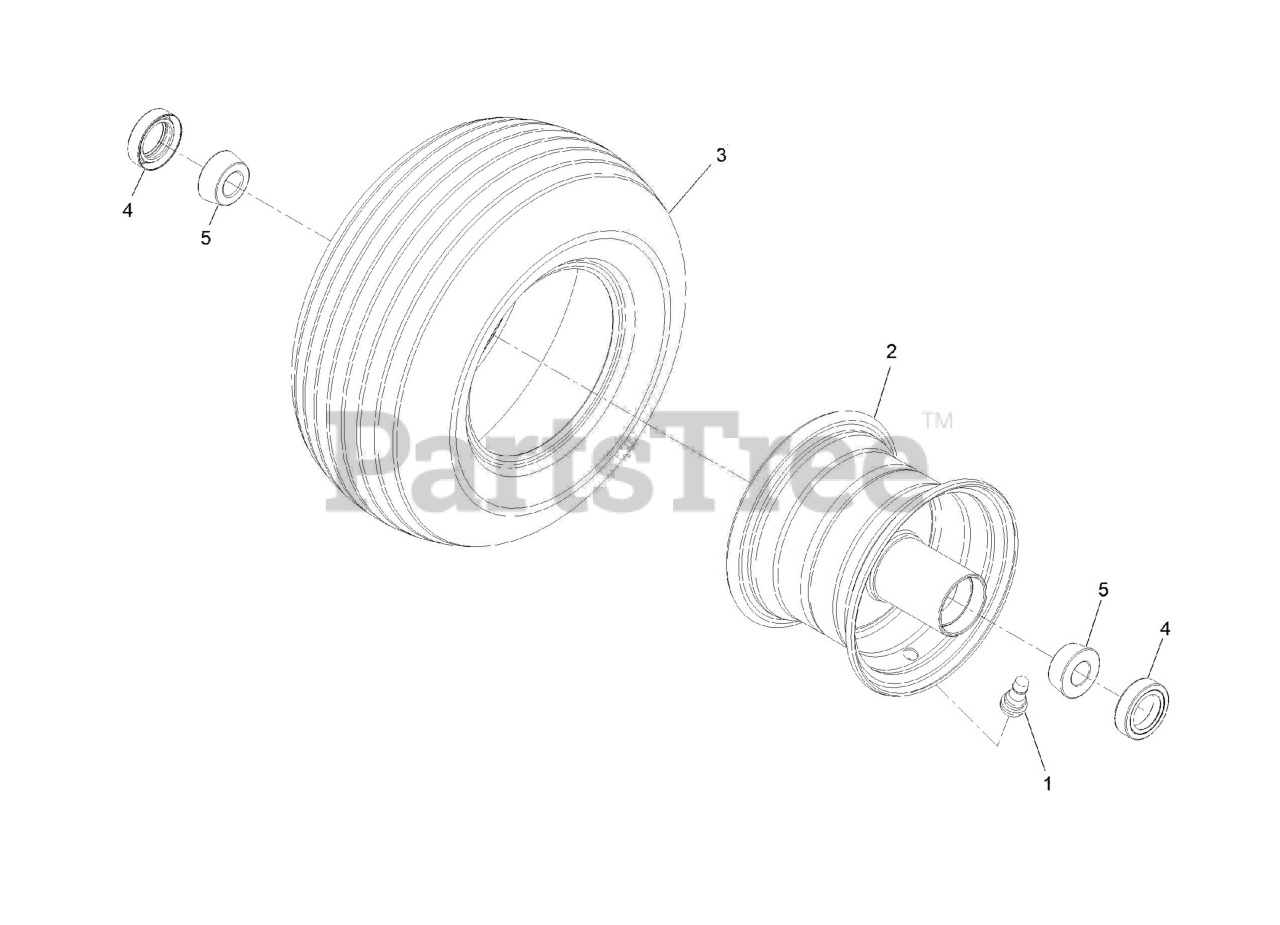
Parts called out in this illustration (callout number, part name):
1	VALVE
2	Rim-6 X 4.5
3	Tire-Rib
4	SEAL-CASTER
5	BEARING-CONE, TAPERED ROLLER
